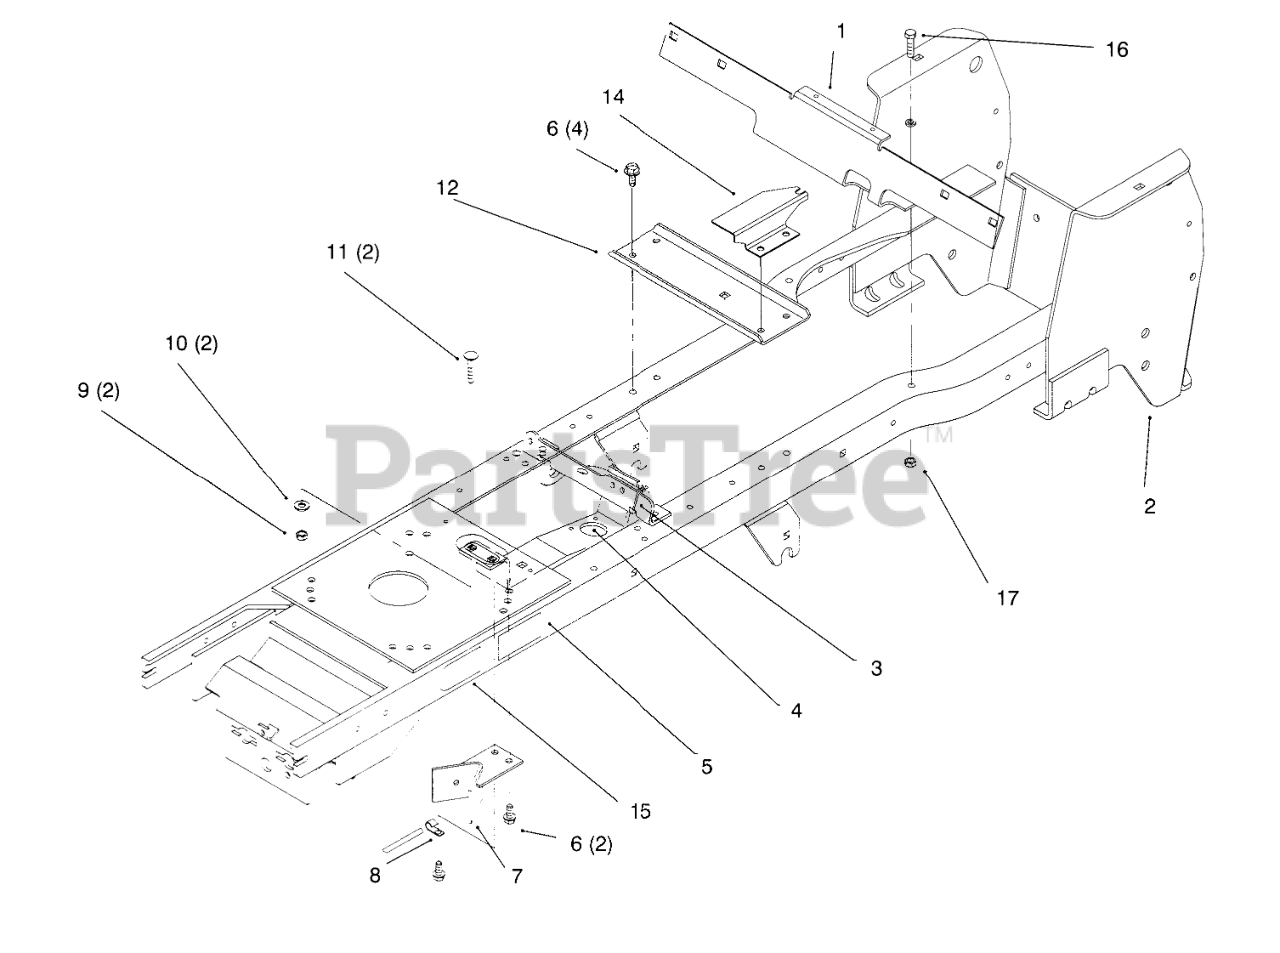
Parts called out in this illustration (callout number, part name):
1	SUPPORT - FENDER
2	Frame W.a.
3	TIE-CABLE
4	STEERING BRKT WA
5	DECAL-INSTALL BELT
6	SCREW-HWHTF
7	WLDMT-PTO STOP
8	CLIP
9	NUT-LOCK, NI
10	WASHER-PLAIN
11	BOLT-CARR
12	BRACKET-IDLER PLATE
14	BRACKET-HOC GAGE
15	DECAL-ATTACH A-MATIC
16	SCREW-HH
17	NUT-LOCK, NI
